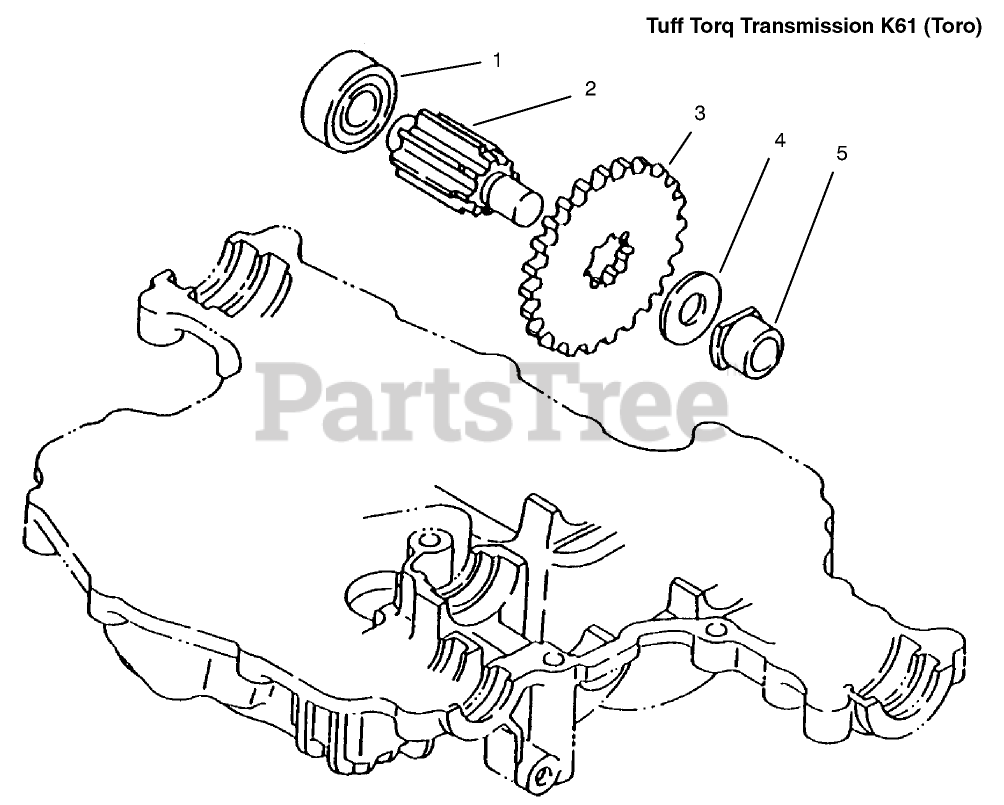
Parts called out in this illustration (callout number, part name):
2	SHAFT - FINAL PINION
3	GEAR-FINAL SHAFT
4	WASHER
